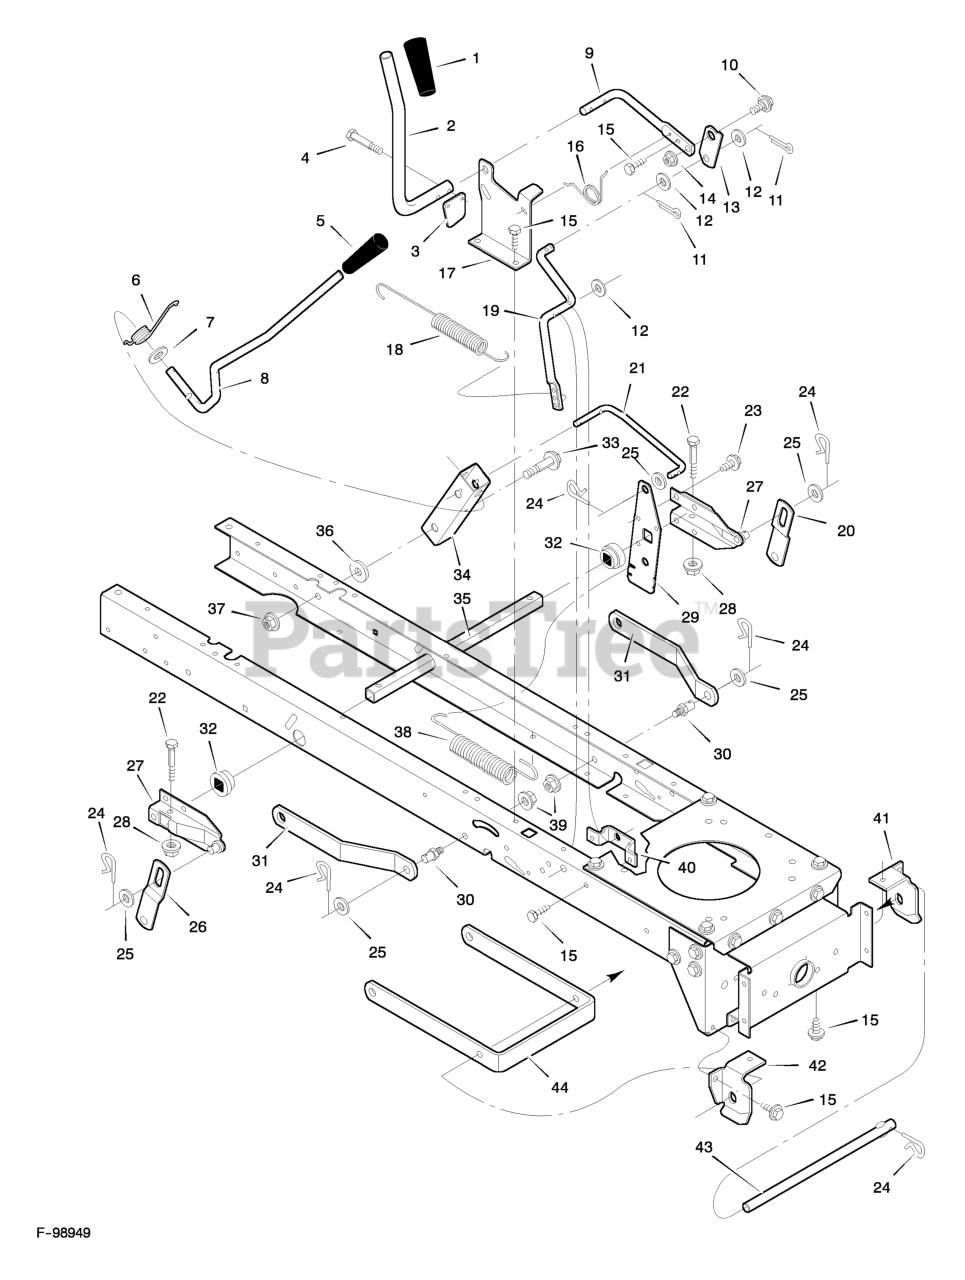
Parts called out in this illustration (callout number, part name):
1	Grip
3	Pad, Switch
4	Screw, Hex
5	Grip
8	Lever, Lift
9	Lever, PTO
10	Bolt, Shoulder
11	Pin, Cotter
12	Washer
13	Link, PTO
14	Nut, Flange
17	Bracket, PTO
19	Crank, PTO
20	Link, Left Lift
21	Link, Lift
24	Pin, Hair
26	Link, Right Lift
27	Lever Assembly, Lift
28	Nut, Flange
29	Plate, Lift Arm
30	Pin
31	Bracket, Rear Suspension
32	Bushing
33	Bolt, Shoulder
34	Bracket, Pivot
35	Tube, Deck Lift
37	Nut, Flange
39	Nut, Flange
40	Bracket, PTO
41	Hanger, Left Deck
42	Hanger, Right Deck
43	Rod, Hanger
44	Bracket, Suspension
